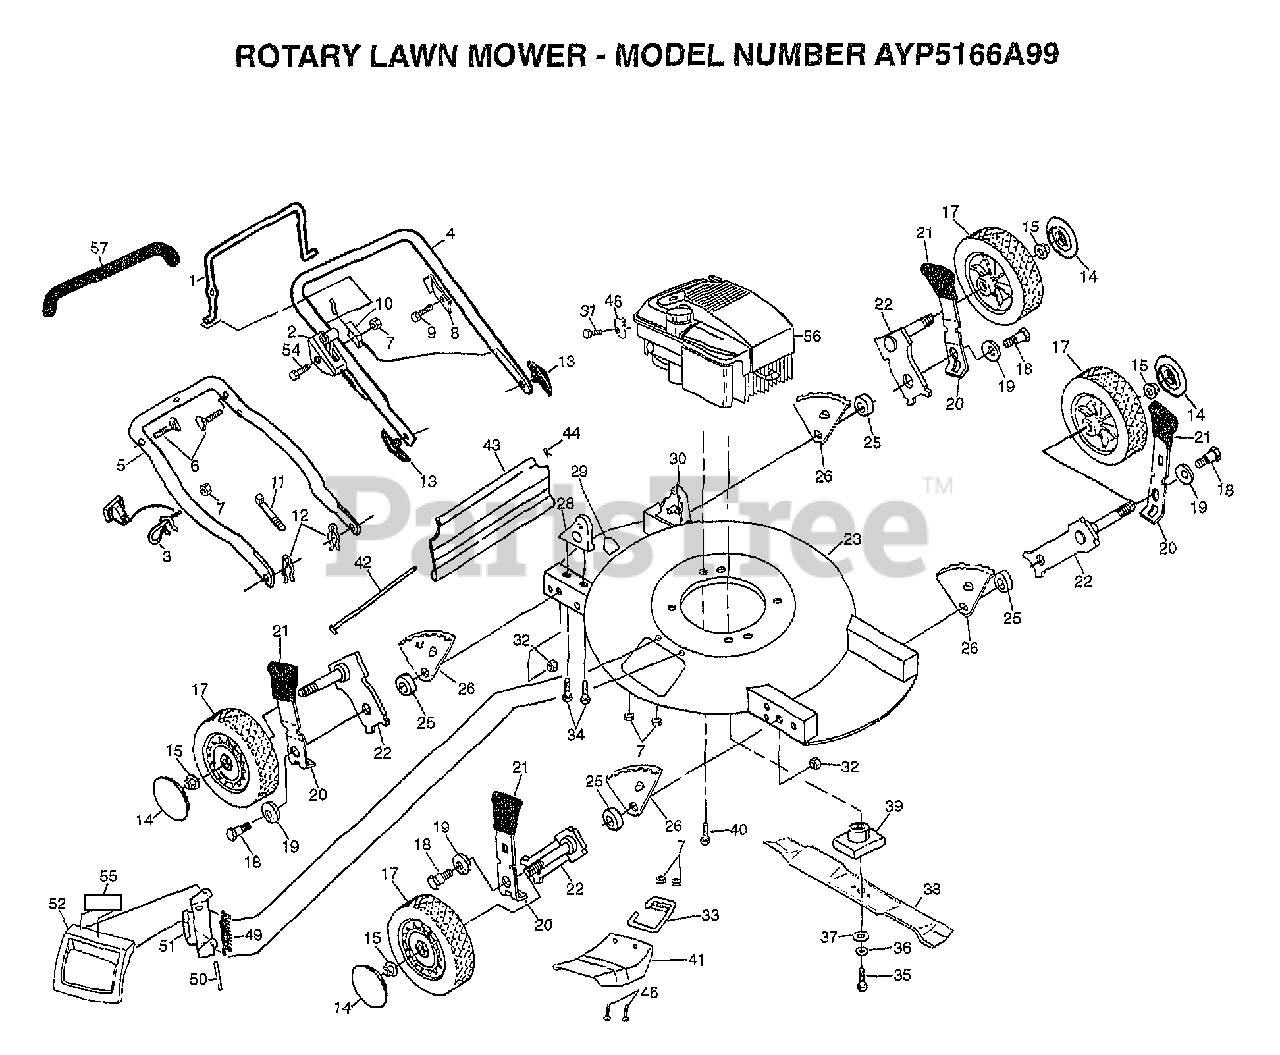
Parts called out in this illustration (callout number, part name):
1	CONTROL BAR PM
2	CONTROL.THL.49.35
3	ROPE GUIDE
4	HANDLE.UPPER.STAND.
5	HANDLE LOWER
6	BOLT.HANDLE.LM
8	"BRKT,UPSTOP"
9	TAPPING SCREW
10	"CABLE,ENG ZONE CO"
12	HAIRPIN COTTER
13	KNOB HANDLE
14	HUB CAP
15	HEX FLANGE LOCKNT
17	WHEEL.8X1.75.WHT
18	BOLT SHLD 3/8-16
19	"WASHER, BELLEVIL."
20	SPRING SELECTOR
21	KNOB PM
22	ARM.AXLE.ASM.BZP.
25	SPACER.HEIGHT.ADJ
26	BRACKET.ADJ.9POS.
28	HDLE BRKT ASSY.RH
29	DECAL-DANGER PM
30	HDLE BRKT ASSY LH
31	SCREW PM
32	LOCKNUT PM
33	BRACKET.CHUTE.MTG
34	SCREW 5/16-18X3/4
35	SCREW
36	LOCKWASHER
37	"WASHER,HARDEN"
38	BLADE.20.MULCH.AY
39	ADAPTOR.BLADE.LM
40	BOLT.ENG.3/8-16
41	"DEFL,MULCHER"
42	ROD-DEFLECTOR
43	"SKIRT-REAR,20"""
44	RETAINER CLIP
45	CABLE CLAMP
49	SPRING-TORSION
50	ROD.HINGE.COMBI-C
51	BRACKET PM
52	DOOR-MULCHER
54	SCREW.HXHD.WASH.
55	DECAL.CHUTE.MULCH
57	GRIP.HANDLE.FOAM
